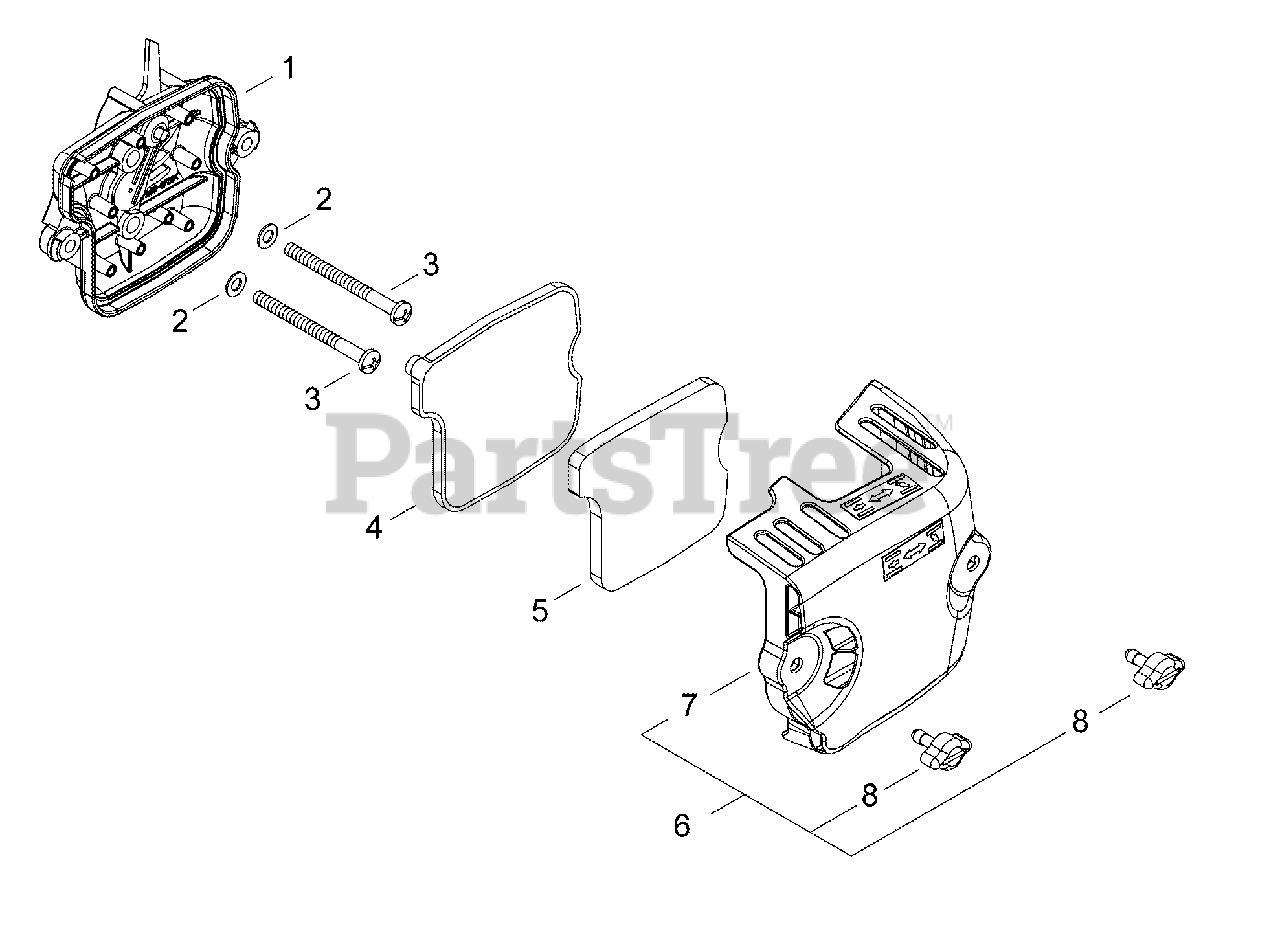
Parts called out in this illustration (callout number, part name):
1	CASE ASSY, AIR FILTER
2	WASHER 5 MM
3	SCREW M5×60
4	FILTER, AIR
5	PRE-FILTER, FOAM
6	COVER ASSY, AIR FILTER
7	COVER, AIR FILTER
8	THUMBSCREW M5
